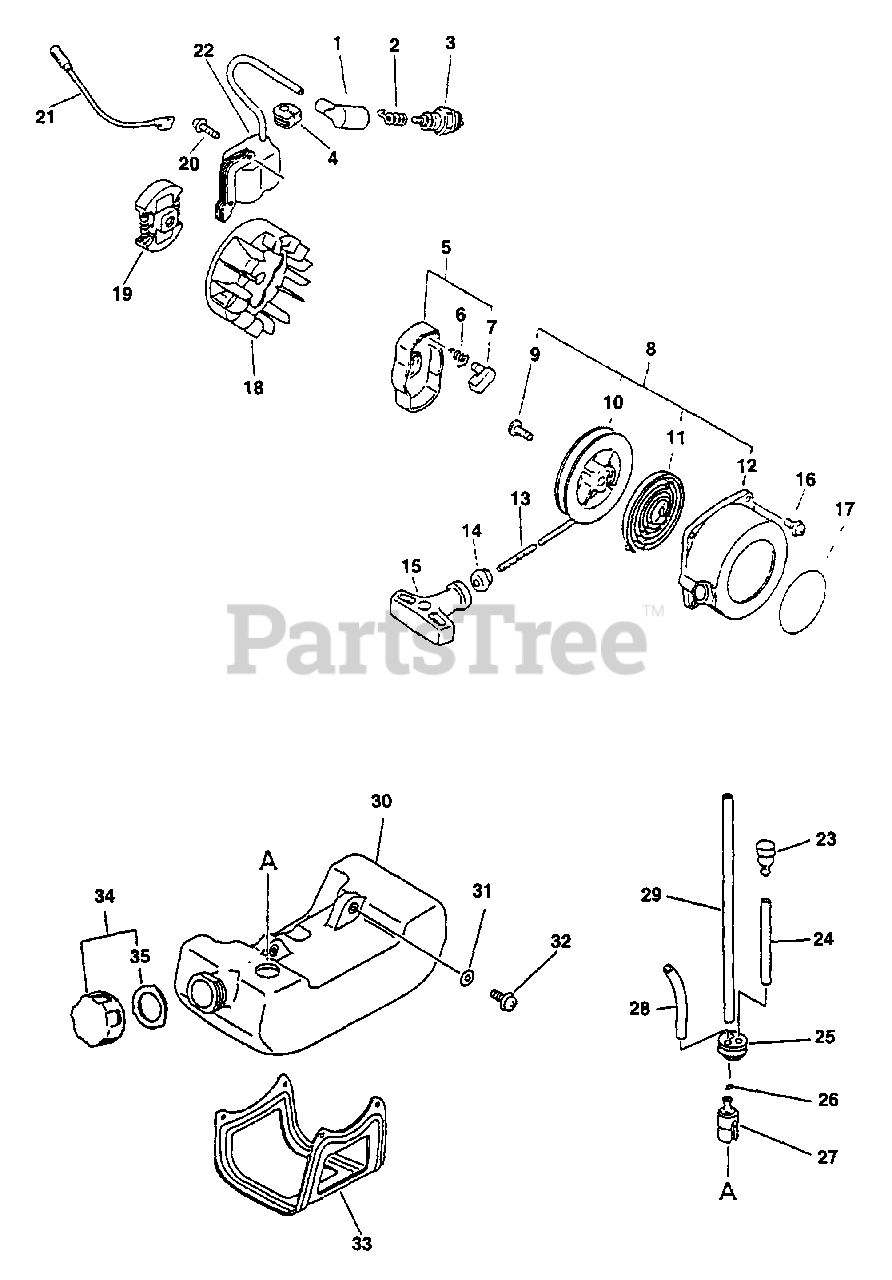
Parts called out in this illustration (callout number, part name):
1	CAP, SPARK PLUG
2	TERMINAL, SPARK PLUG
3	SPARK PLUG - BPM-7Y
3	SPARK PLUG - BPMR7A
5	PAWL ASSY, STARTER
6	SPRING, RETURN
7	PAWL, STARTER - BLACK
8	STARTER ASSY, RECOIL
9	SCREW
10	REEL, ROPE
11	SPRING, RECOIL
12	CASE, RECOIL STARTER
13	ROPE, STARTER
14	GUIDE, ROPE
15	GRIP, STARTER
16	BOLT 4×16
17	LABEL, ECHO
18	FLYWHEEL
19	CLUTCH ASSY
20	SCREW 4×22
21	LEAD - GROUND
22	COIL, IGNITION
23	VENT ASSY
24	PIPE, FUEL 3x-5x-70 BLACK
25	GROMMET, FUEL
26	CLIP 6 MM
27	FILTER, FUEL
28	PIPE, FUEL RETURN 3×6×90 MM CLEAR
29	PIPE, FUEL 3x-5x-180
30	TANK, FUEL
31	WASHER 5.5×12×0.8
32	SCREW 5×16
33	GUARD, FUEL TANK
34	CAP ASSY, FUEL
35	GASKET, FUEL CAP
